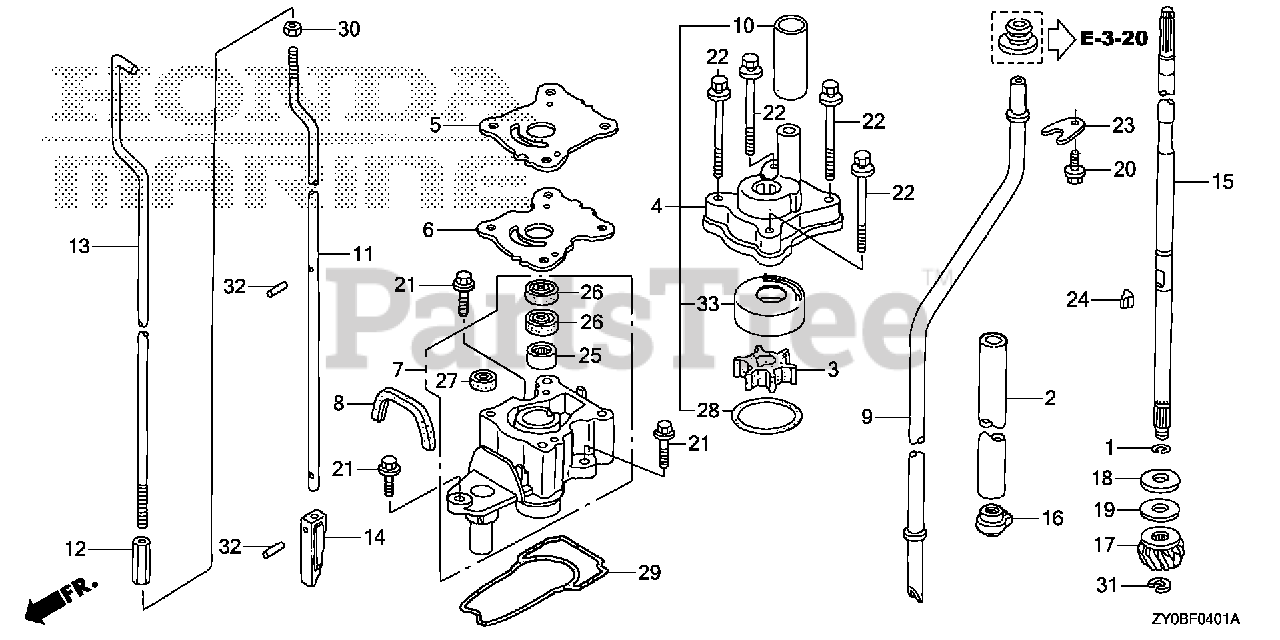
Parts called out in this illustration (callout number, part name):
1	CLIP, VALVE GUIDE
3	IMPELLER, PUMP (UL)
4	HOUSING ASSY., IMPELLER
5	COVER, IMPELLER
6	GASKET, IMPELLER
9	TUBE, WATER (UL)
10	RING, WATER TUBE SEAL
11	ROD B, SHIFT (UL)
12	JOINT, SHIFT ROD
13	ROD A, SHIFT (L)
16	SLINGER, OIL (UL)
17	GEAR, PINION
18	WASHER A, THRUST BEARING
19	WASHER B, THRUST BEARING
19	WASHER C, THRUST BEARING
20	BOLT, FLANGE (6X12) Use from Frame SN 1005249.
21	BOLT, FLANGE (6X20) (ENGINE NO.)
22	BOLT-WASHER (6X90)
23	PLATE, WATER TUBE SETTING
24	KEY, WOODRUFF
25	BEARING, NEEDLE (15X21X12)
26	SEAL, WATER (15X24X5)
27	SEAL, WATER (6MM)
28	O-RING (42.2X2.4)
29	O-RING, WATER PUMP HOUSING
30	NUT, HEX. (6MM)
31	E-RING (8MM)
32	ROLLER (2.5X11.8)
33	LINER, PUMP
